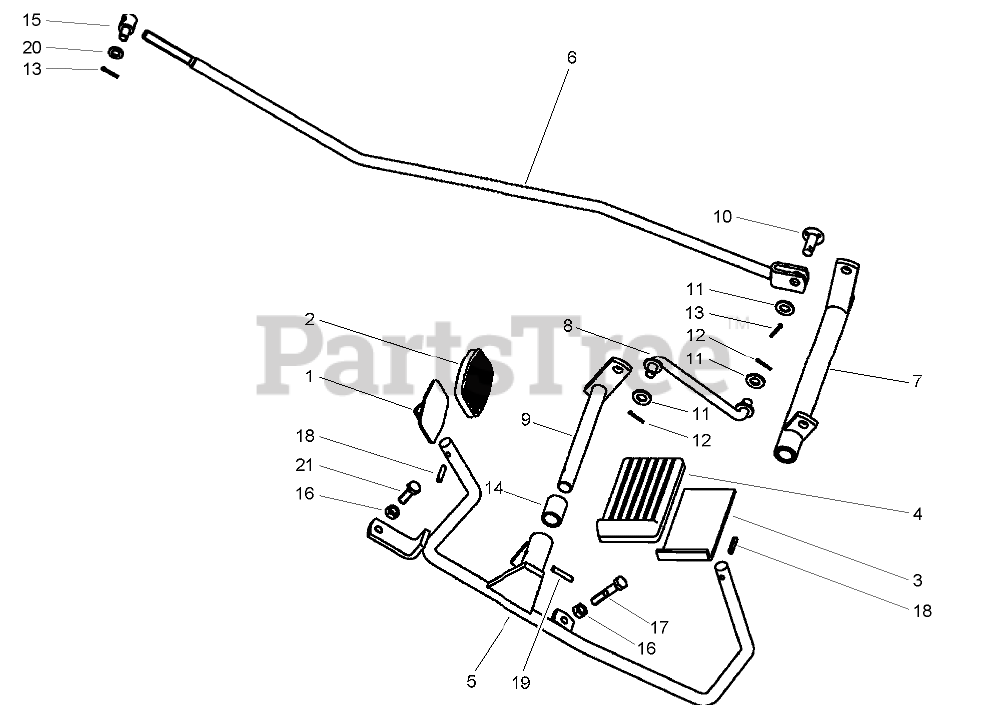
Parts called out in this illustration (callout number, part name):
1	PEDAL-REAR, TRAVEL
2	PAD-PEDAL
3	PEDAL-TRAVEL, FRONT
4	PAD-PEDAL, FRONT
5	ROD-TRAVEL
6	ROD-TIE
7	SHAFT-DIAGONAL
8	LINK-FORMED
9	SHAFT-DIAGONAL
11	WASHER-FLAT
12	PIN-COTTER
13	PIN-COTTER
14	SPACER
16	NUT-HEX
17	CAPSCREW-HH
18	PIN-SPRING
19	PIN-SPRING
20	WASHER
21	SCREW-HH
